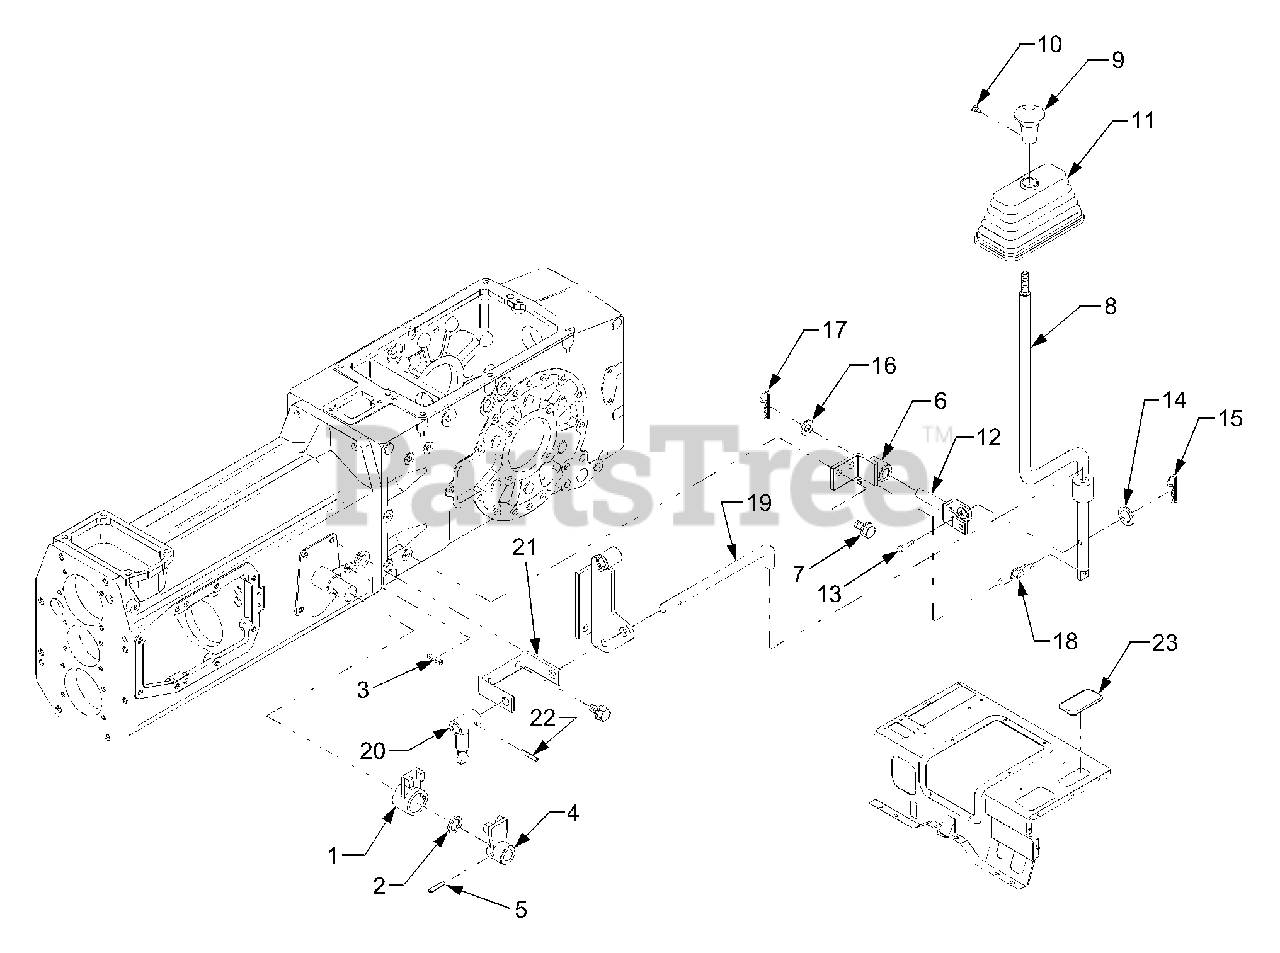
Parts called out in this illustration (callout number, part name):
1	Lever 1, Hi-Low
2	Washer, Plain
4	Lever 2, Hi-Low
8	Lever, Hi-Low
9	Grip
14	Washer, Plain
16	Washer, Plain
21	Bracket, Hi-Low Rod
